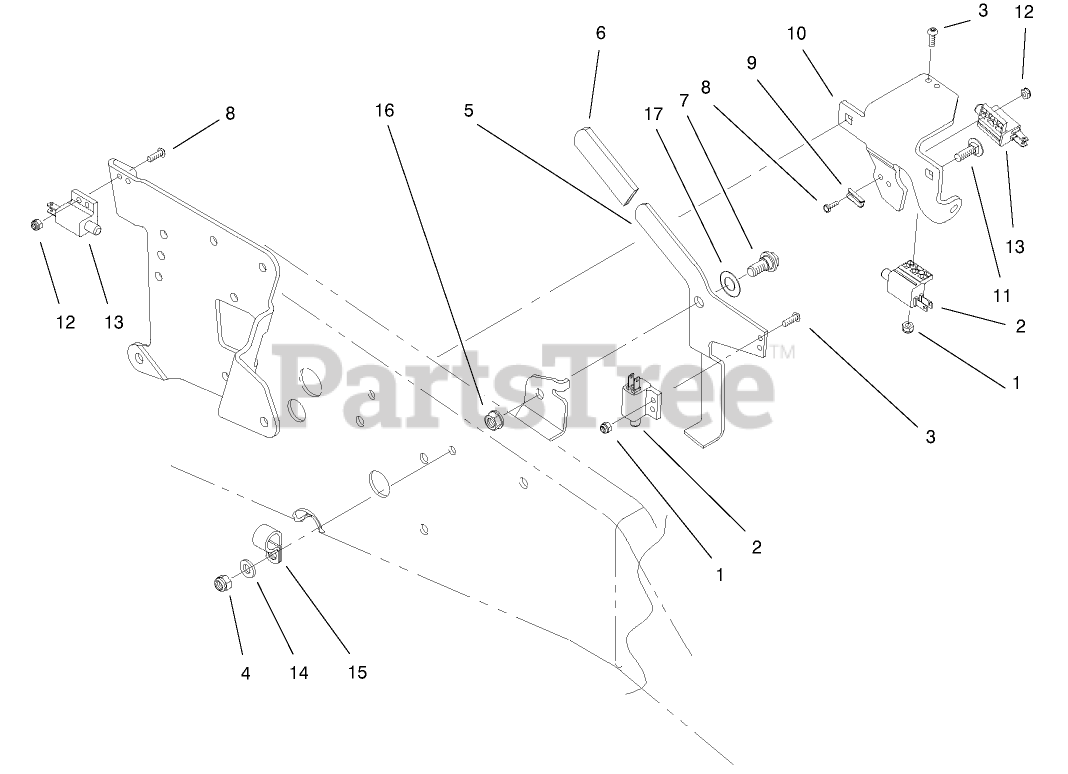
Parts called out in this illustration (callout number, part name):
1	NUT-LOCK, NI
3	SCREW-HSH
4	NUT-LOCK, NI
5	LATCH-BRAKE, PARKING
7	BOLT-SHOULDER
8	SCREW
9	RETAINER-SCREW
10	BRACKET-SWITCH
11	SCREW-CARR
12	NUT-LOCK
13	SWITCH-POLE, SINGLE
14	WASHER-PLAIN
15	CLAMP - R
16	NUT-HEX
17	WASHER
